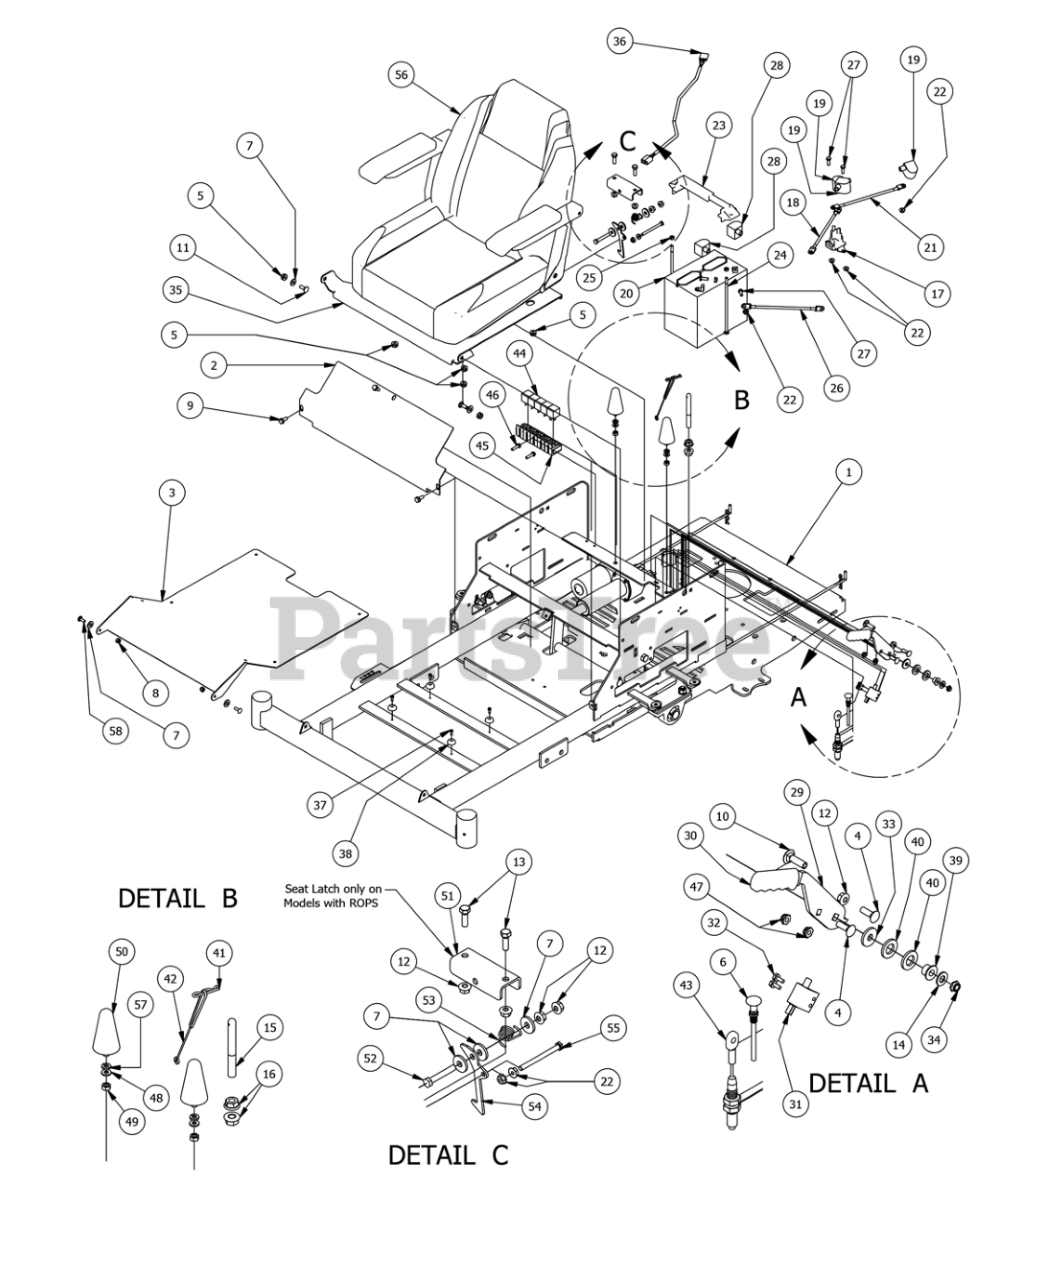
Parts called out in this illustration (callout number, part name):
1	ZT/CZT Frame 2013 Models
2	2013 ZT/CZT Cooler Cover
3	ZT/CZT FLOOR PANEL
4	5/16" x 1" Carriage Bolt
5	5/16-18 Nylon Flange Nut
7	.360 ID Plastic Washer
8	1/4" Nylock Nut
9	5/16 x 3/4 washer head type F screw
10	3/8" x 1 1/4" Carriage Bolt
11	5/16" x 7/8" Carriage Bolt
12	5/16" Flange Nut
13	5/16" x 1" Bolt
14	3/8" Flat Washer
15	Seat Braket Pin
16	1/2" Flange Nut
18	24 in red battery cable
21	12 in red battery cable
22	1/4-20 Hex Flange Nuts Zinc w/Serrations
23	Battery Hold Down
24	1/4-20 X 8 Carriage Bolt
25	1/4-20 Hex Nut
26	Starter to chassis cable
27	1/4-20 x 3/4 GR 5 Hex Bolts Zinc
28	Black Boot For ground cable
29	Brake Handle Cam Over
30	Rubber Brake Grip-cZT/ZT 2013
31	Safety Switch
32	12-24x 1/2 HWH Bolt
33	.390 ID Plastic Washer
34	3/8 Nylock Jam Nut 1/2 Nut
35	2013 ZT Seat Plate
36	Seat Switch Adapter
37	#10 x 1/2" Self Taping Screw
38	Button Bumper
39	Bronze Bushing SF-1220-8
40	.635 ID Plastic Washer
41	Seat latch pin
42	seat pin lanyard
43	Brake Cable
44	Relay Terminal
45	Harness-ZT Only 2008 and up
46	1/4 x 1 Hex Head tek screw
47	5/16-18 Nylock Jam Nut 1/2 Nut
48	1/4" Flat Washer
50	Rubber Cone-1621-153
51	ZT/CZT Seat Latch Bracket
52	5/16-18 X 2 Hex C/S (GR.5) ZC
53	Torsion Spring for Seat latch
54	Seat Latch Lever
55	1/4 x 3 Hex Bolt - Grade 8 - ACS
56	2014 ZT Seat Black/Orange
57	5/16" Lock Washer
58	1/4" x 3/4" Carriage Bolt
